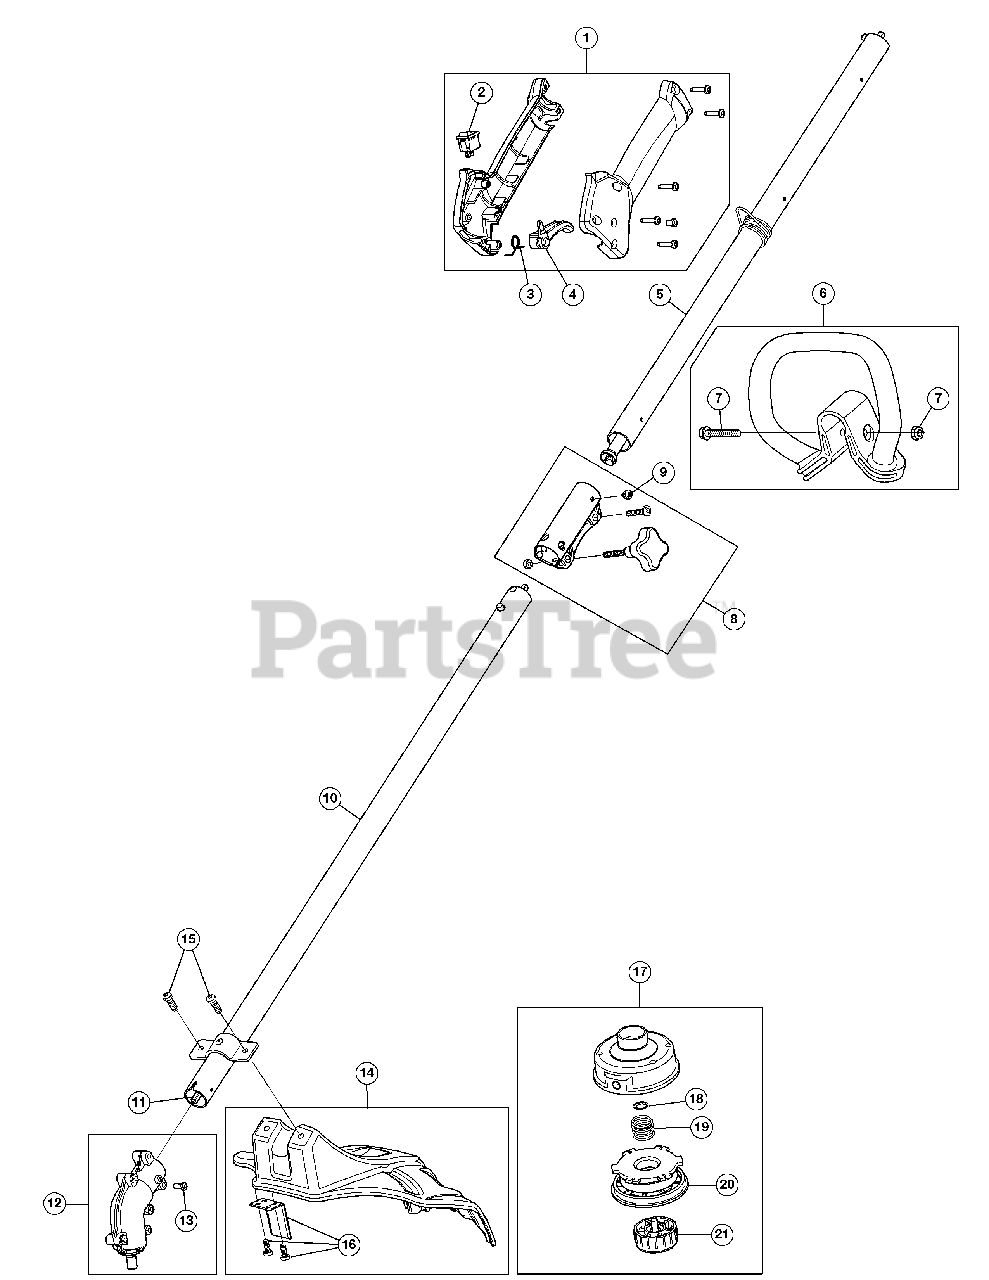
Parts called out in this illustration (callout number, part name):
1	Throttle Housing Assembly (Incl. 2 - 4)
2	Switch Assembly
3	Throttle Trigger Spring
4	Throttle Trigger
5	Upper Drive Shaft Housing Assembly
6	D-Handle (Incl. 7)
7	D-Handle Bolt
8	Split Boom Coupler (Incl. 9)
10	Lower Drive Shaft Housing Assembly
11	Lower Flexible Drive Shaft
12	Gear Box Assembly (Incl. 13 & 17 - 21)
13	Anti-Rotation Screw
14	Shield Assembly (Incl. 15 & 16)
15	Shield Mounting Screws
16	Blade Assembly
17	Outer Spool Assembly
20	Inner Reel
21	Bump Knob Assembly
